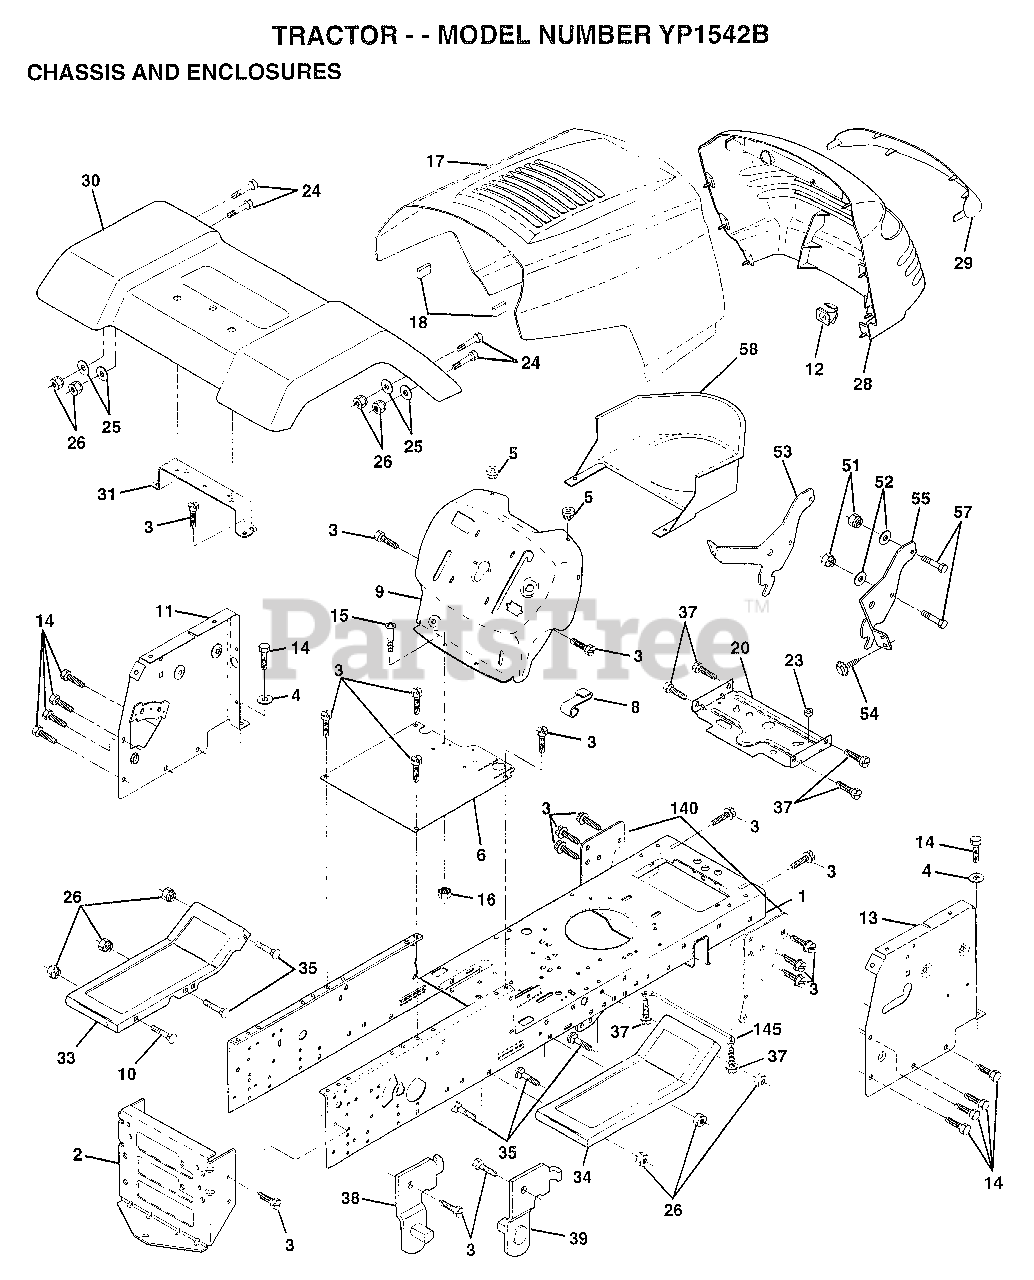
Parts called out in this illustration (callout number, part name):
3	SCREW
4	WASHER
5	BUMPER-HOOD/DASH
6	SADDLE
8	CLIP.RETAINER
9	DASH.SILKSCREEN
11	"PANEL-DASH,LH"
12	CLIP.TINNERMAN
13	"PANEL DASH,RH"
14	SCREW LT
17	"HOOD W/TRIM,MS428"
20	"PLATE-MTG,BATT/FU"
24	BOLT
25	WASHER
26	NUT
28	GRILL
29	LENS.EURO.W/DECAL
30	FENDER ASM
31	BRKT FENDER
33	FOOTREST PNT LH
34	FOOTREST.RH.LT/GT
35	BOLT
38	BRACKET ASM LH
39	BRACKET ASM RH
51	NUT
52	WASHER
53	BRACKET.GRILLE.LH
54	SCREW.HEX.WS.HD
55	BRACKET.GRILLE.RH
58	AIR DUCT
140	BRKT SUSPENSION
145	"ROD POVOT,CHASSIS"
